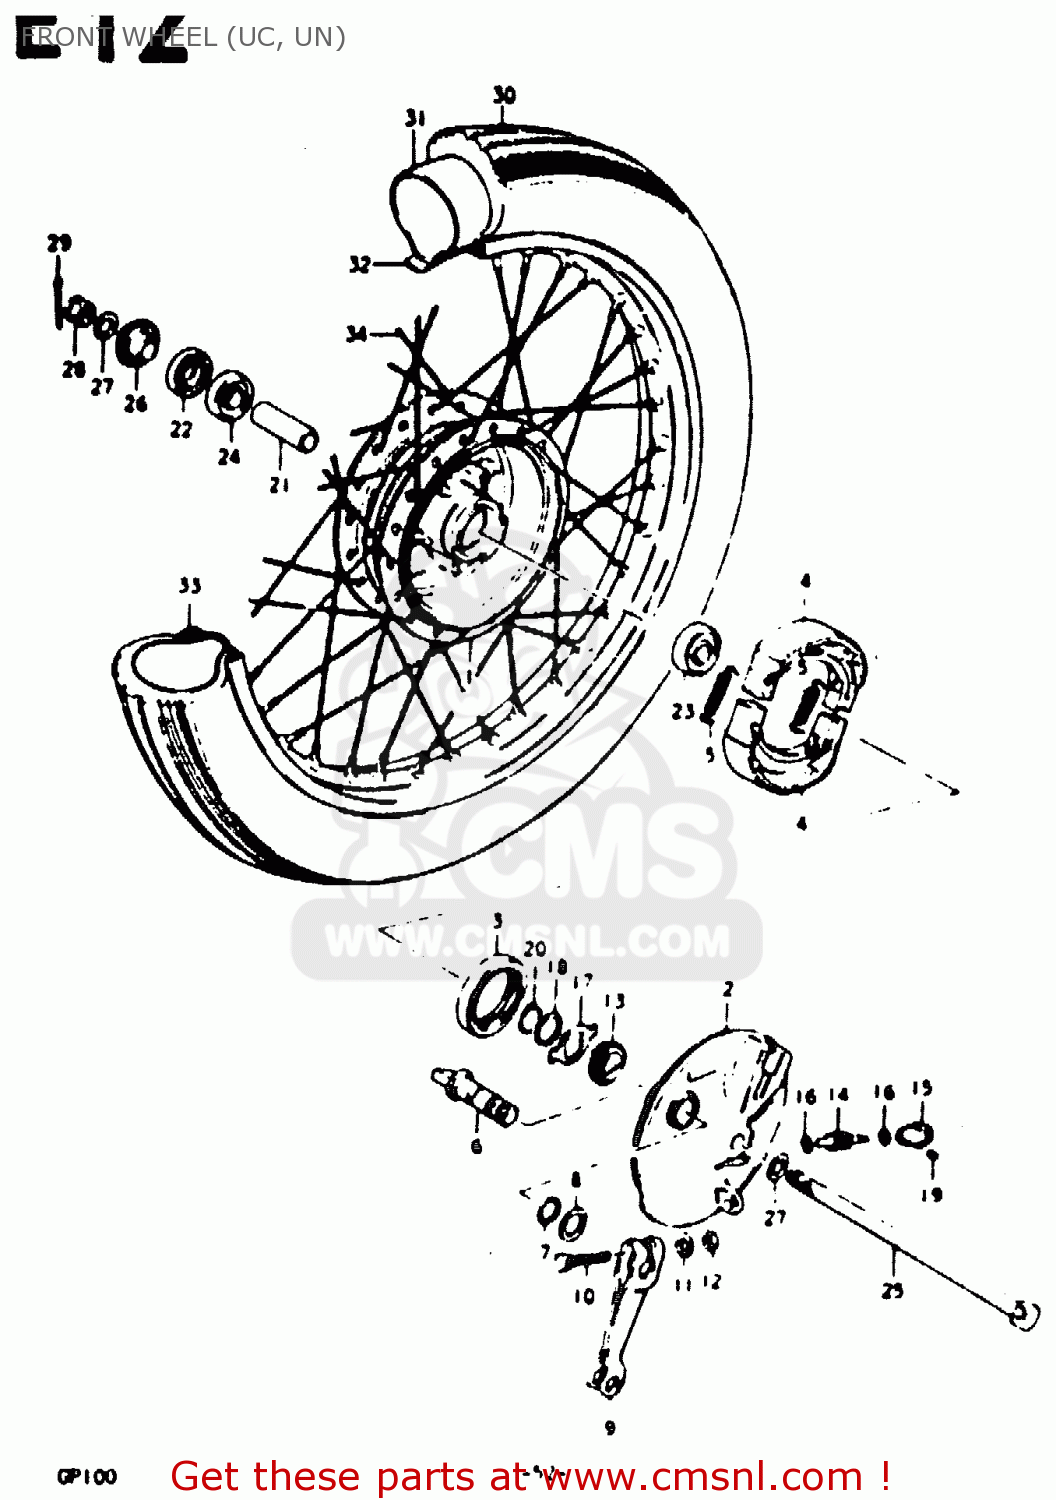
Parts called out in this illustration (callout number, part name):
1	HUB,FRONT
2	PANEL, FRONT HUB
3	OIL SEAL (43X58X7)
4	SHOE,BRAKE
5	SPRING(L:34)
6	CAM,FRONT BRAKE
7	O-RING (D:2.4 ID:13.8)
8	WASHER (14.5X22X1.6)
9	LEVER,FR BRAKE CAM
10	BOLT(6X35)
11	WASHER
12	NUT
13	GEAR, SPEEDOMETER (NT:26)
14	PINION,SPEEDOMETER
15	BUSH,METER GEAR OUTER
16	WASHER (5.1X9X0.4)
17	DRIVER,SPEEDOMETER GEAR
18	WASHER(16X22X1)
19	SCREW
20	CIRCLIP,15MM
21	SPACER (10.2X16X51)
22	SEAL,OIL(15X31X5)
23	BEARING
24	BEARING
25	AXLE,FRONT
26	SPACER,FRONT AXLE,RIGHT
27	WASHER
28	NUT
29	COTTER PIN
30	TIRE,FRONT
31	TUBE,INNER
32	PROTECTOR,WHEEL,INNER
33	RIM,WHEEL(1.40X18)
34	SPOKE SET
